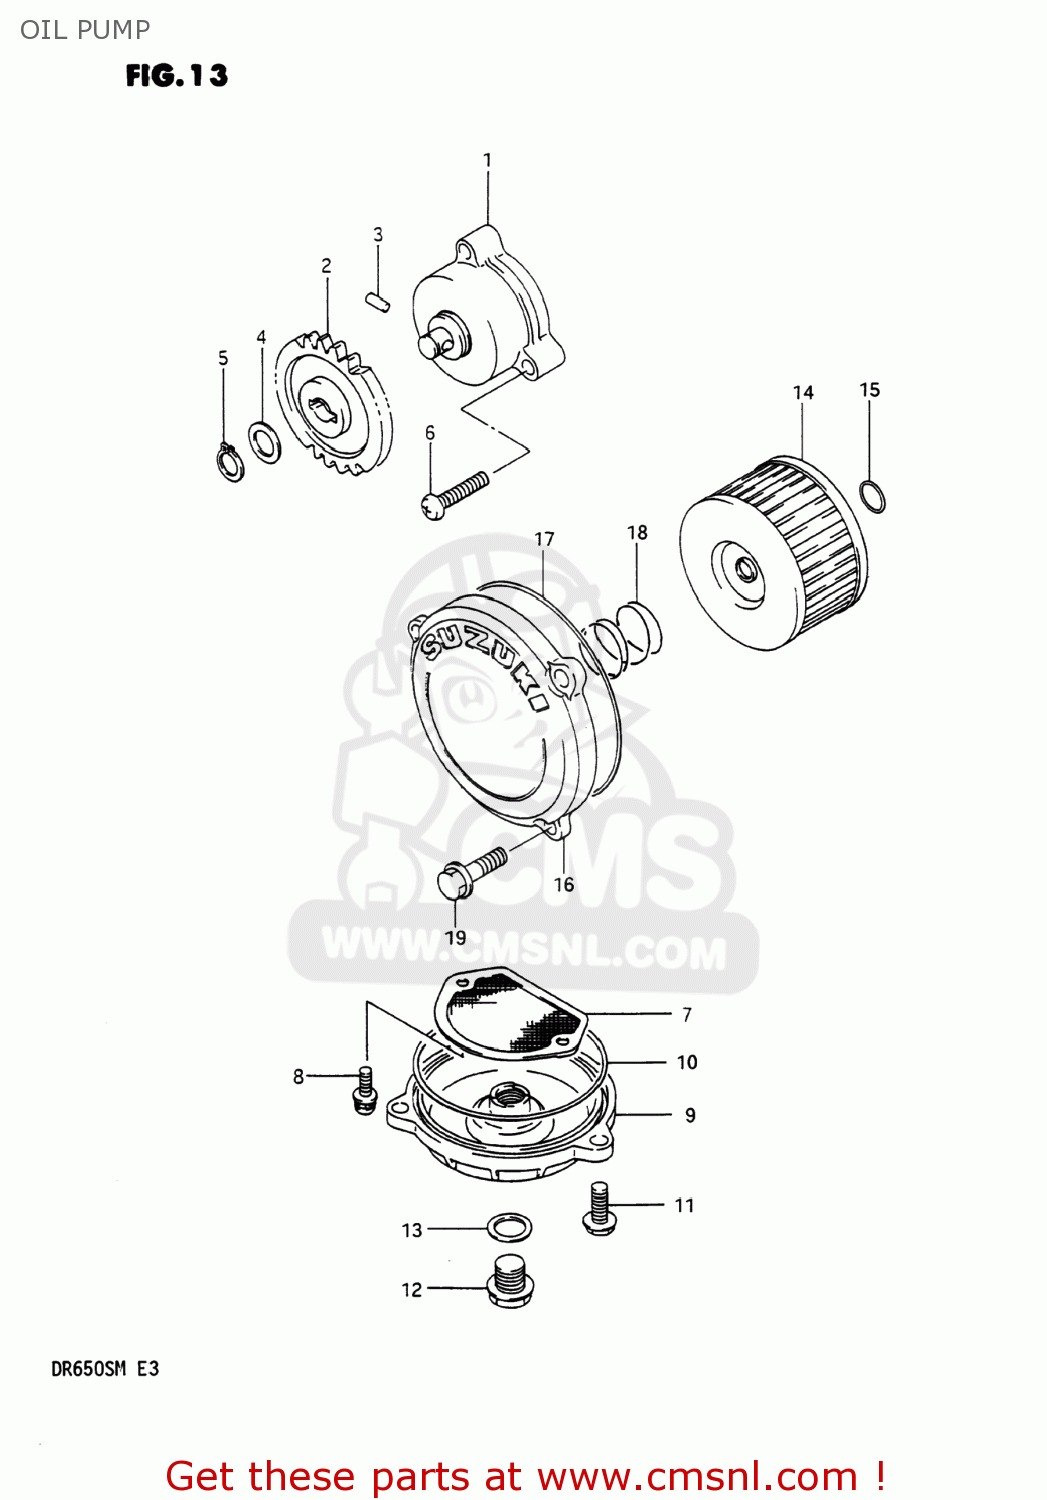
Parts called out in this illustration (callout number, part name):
1	PUMP ASSY,ENGINE OIL
2	GEAR,OIL PUMP DRIVEN
3	PIN(4X15.8)
4	SHIM
5	CIRCLIP
6	SCREW
7	STRAINER,ENGINE OIL
8	SCREW
9	CAP,OIL STRAINER
10	O RING(D:2.4,ID:85)
11	BOLT 6X20
12	PLUG
13	GASKET(14X19.2X2) (NAS)
14	FILTER,ENGINE OIL
15	O RING(D:2.4,ID:15.8)
16	CAP,OIL FILTER
17	O RING(D:2.4,ID:73)
18	SPRING
19	BOLT
